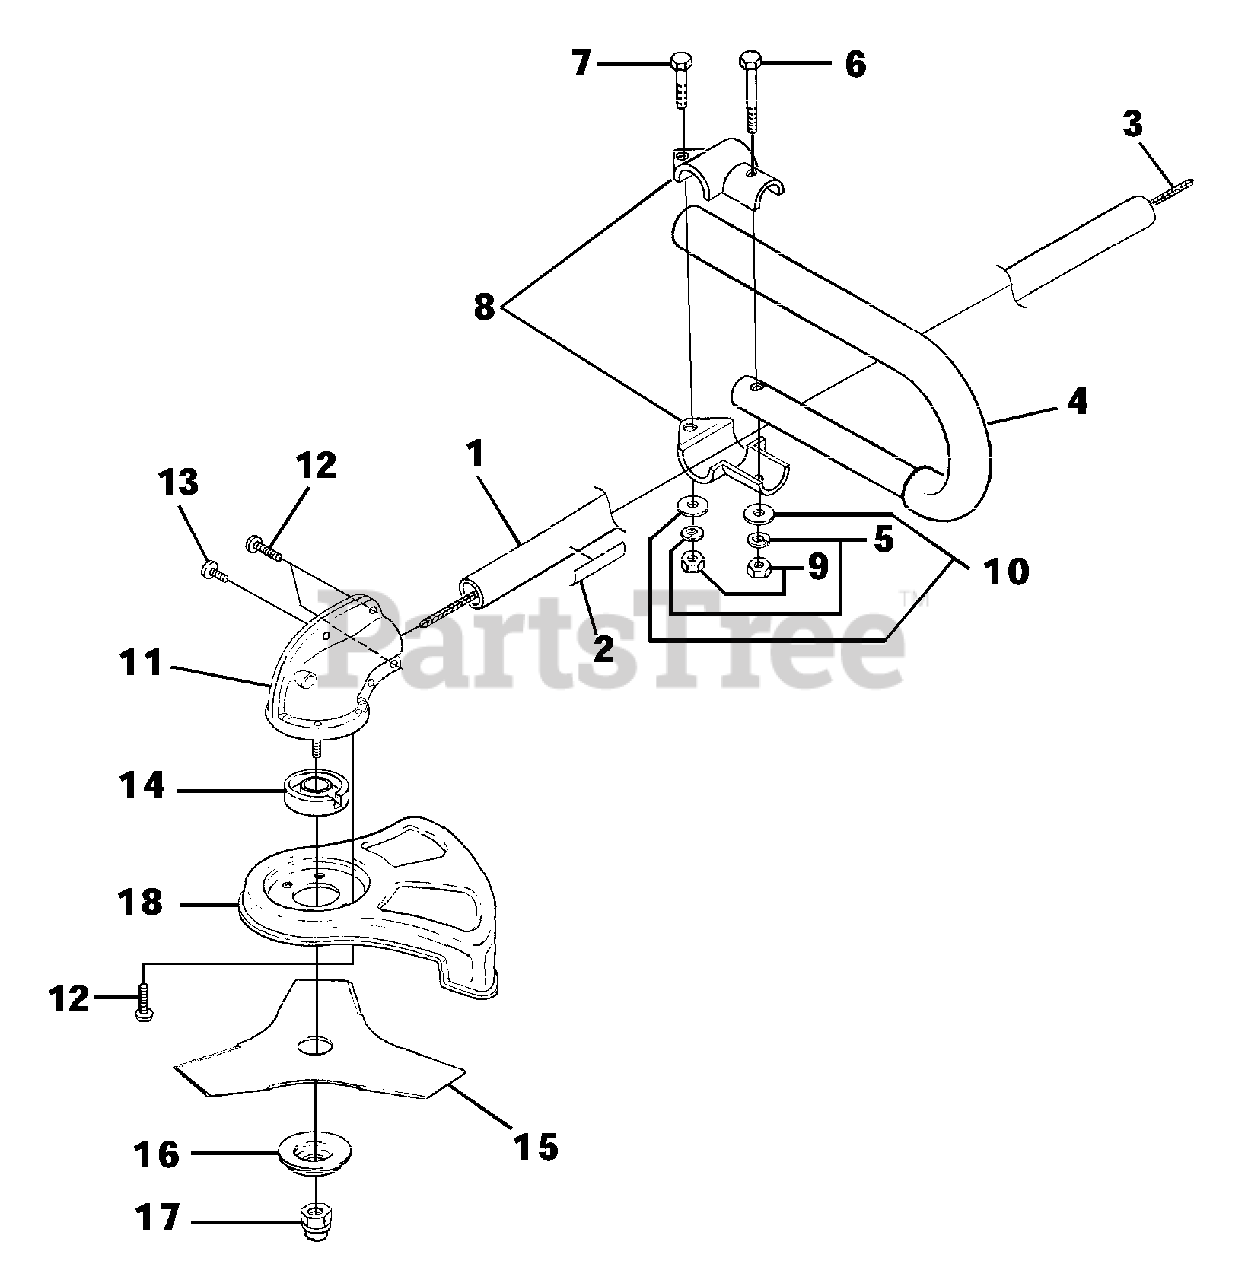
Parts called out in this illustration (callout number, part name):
1	DRIVESHAFT HOUSING
2	DECAL-Warning
3	SHAFT-Flexible
4	FRONT HANDLE ("J")
5	WASHER-Lock (1/4")
6	SCREW-Hex Hd. (1/4-20 X 1/2")
7	SCREW-Hex Hd. (1/4-20 X 1")
8	CLAMP-Handle Bar
9	NUT-Hex (1/4-20)
10	WASHER-Flat (1/4")
11	GEAR HEAD
12	Screw, Taptite Hex Hd. (10-24 x 1/2")
13	Screw-Hex Hd. (10-24 x 5/8")
14	WASHER-Flanged
15	BLADE-Tri-Arc(TM) (8")
16	WASHER-Cupped
17	NUT-Hex Locking (R.H.)
18	BLADE GUARD
